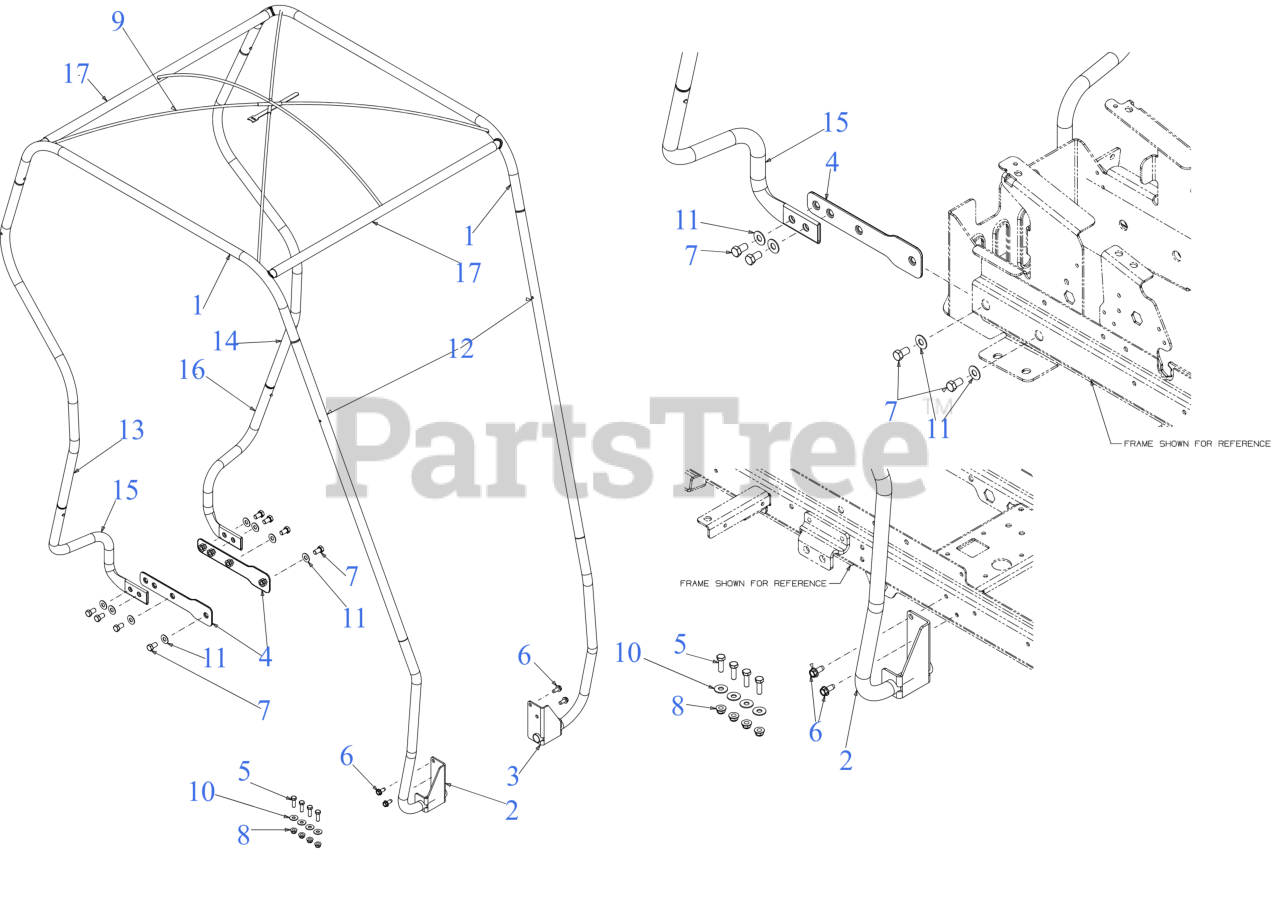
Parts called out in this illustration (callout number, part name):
1	SUPPORT TUBE ASSEMBLY
2	RIGHT FRONT BOTTOM SUPPORT
3	LEFT FRONT BOTTOM SUPPORT
4	MOUNTING BRACKET
5	SCREW 5/16-18 x 1.0 GR5
6	SCREW 5/16-18 x .750
7	SCREW 7/16-14X .750 GR5
8	FLANGE LOCK NUT 5/16-18
9	FLEX CABLE RODS
10	FLAT WASHER
11	FLAT WASHER .444x1.000x.057
12	FRONT RIGHT SIDE SUPPORT
13	RIGHT REAR SUPPORT
14	LEFT REAR SIDE SUPPORT
15	RIGHT REAR BOTTOM SUPPORT
16	LEFT REAR BOTTOM SUPPORT
17	CROSS SUPPORT TUBE
